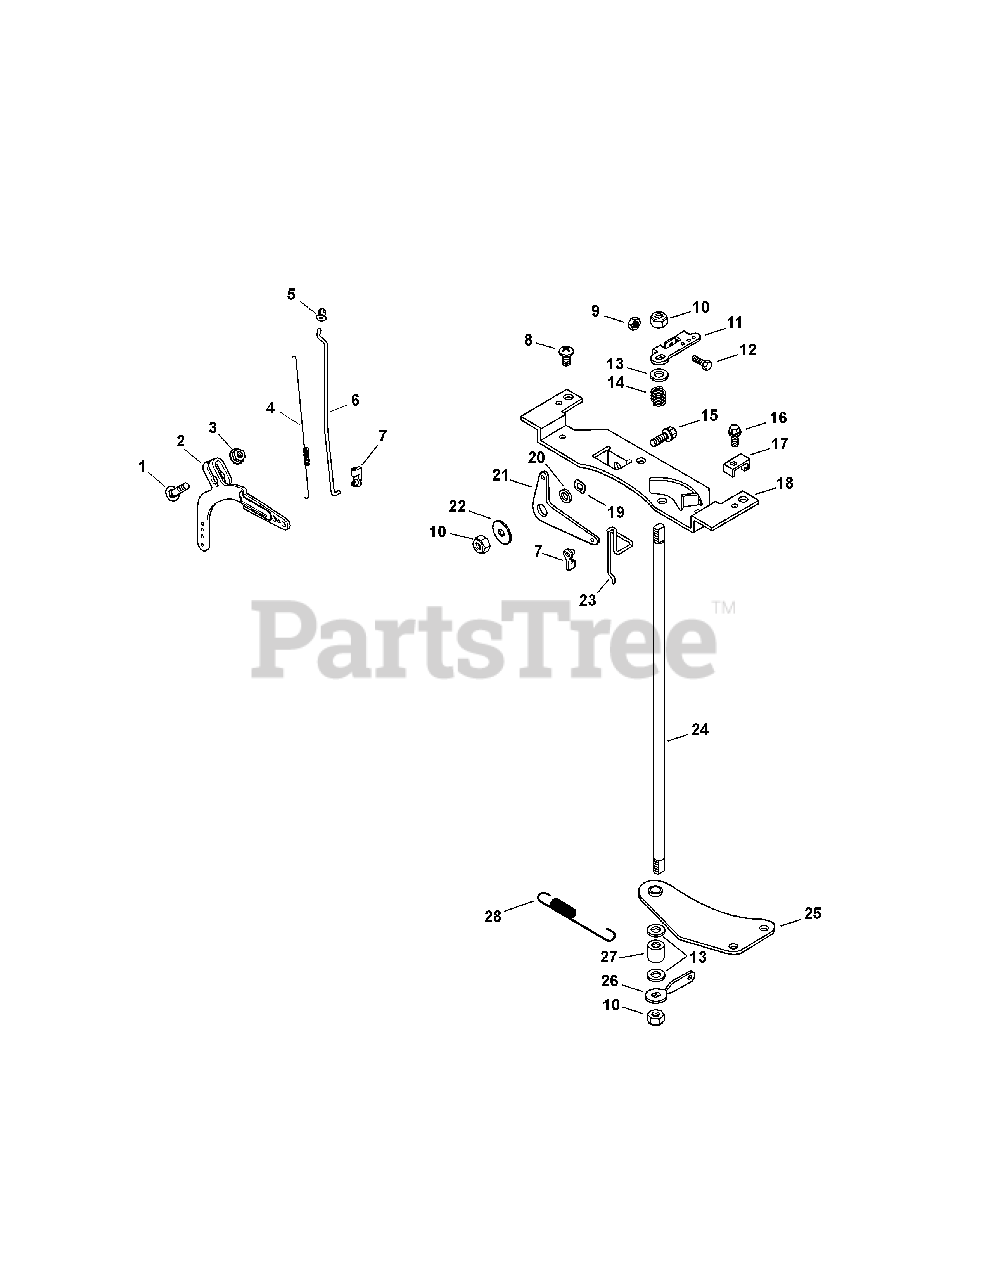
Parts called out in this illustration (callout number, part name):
1	BOLT, RD HD SQ NECK M6X1.0X25
2	LEVER, GOVERNOR
3	NUT, FLG M6X1.0
4	SPRING, LINKAGE
5	BUSHING, LINKAGE RETAINING
6	LINKAGE, THROTTLE
7	BUSHING, THROTTLE LINKAGE
8	SCREW, PHL HD 11-16X3/4''
10	NUT, LOCK M6X1.0
11	LEVER, THROTTLE CONTROL
12	SCREW, CAP M4X.7X30
13	WASHER, FLAT 1/4''
14	SPRING, THROTTLE SHAFT
15	SCREW, FLG M6X1.0X16
16	SCREW, FLG THD FRM M5X0.8X16
17	CLAMP, CABLE
18	BRACKET, CONTROL
19	WASHER, SPRING 3/8''
21	LEVER, CHOKE
22	WASHER, FLAT 1/4''
23	LINKAGE, CHOKE
24	SHAFT, THROTTLE
26	LEVER, THROTTLE CONTROL
28	SPRING, GOVERNOR (ORANGE)
